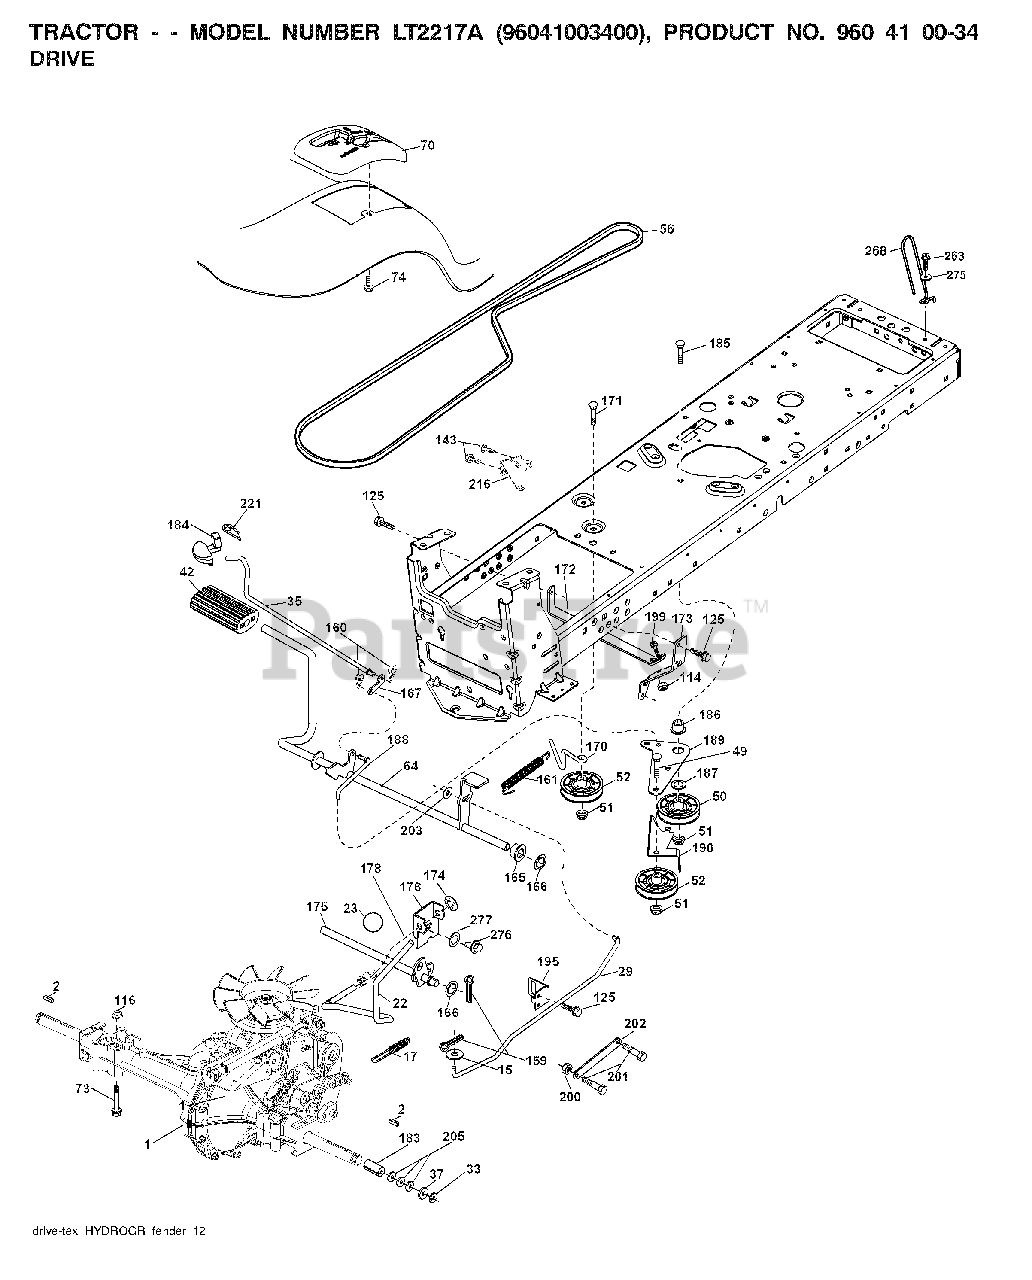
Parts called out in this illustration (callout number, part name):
2	SQUARE KEY
17	SPRING.BRAKE.HG3000/3500
22	ROD.SHIFT.FENDER.TLT.2006
23	KNOB.DUCKHEAD.1/2
29	ROD.BRAKE.HG-0510
33	E-RING LT
35	ROD.BRAKE.PARKING.LT.T
42	PEDAL COVER T
49	BOLT
50	IDLER.FLAT.910.OFFSET
51	NUT LOCK FLG 3/8-16 UNC
52	IDLER.V-GROOVE.910.OFFSET
64	SHAFT.ASM.PEDAL.BRAKE.
70	CONSOLE.SHIFT.STL.HYD.BLACK
73	BOLT.HEX.FLNG.5/16-18X3.75
74	SCREW.HI-LO.CONSOLE
114	NUT.71038.31-18.HEX.NYLOCK
116	NUT LOCK HEX FLANGE 5/16-18
125	SCREW
159	COTTER PIN
160	RETAINER CLIP
161	SPRING.RETURN.CLUTCH.2006
162	SPACER.TRANSAXLE.18&22
165	BUSHING.SHAFT.BRAKE.HAND
166	NUT.PUSH.625.2006
167	LATCH.BRAKE.SPRING
170	KEEPER.V-IDLER.CENTER.
172	STRAP.TRQ.LH.FS.HG0510
173	STRAP TORQUE RH
174	NUT.PUSH.500.2006
175	SHAFT.ASM.SHFT.HG0510/
176	ARM.CLEVIS.ROD.SHIFT
178	SPRING.SHIFT.GT2006
183	SPACER AXLE
184	HANDLE.PAKRING.BRAKE.
186	SPACER.RETAINER
187	WASHER 12/32X2X10GA
188	LINK.CLUTCH.GROUND.DRIVE
189	BELLCRANK.GROUND.DRIVE.TEX.
190	KEEPER.BELLCRANK.DRIVE
195	BRKT.ROD.BRAKE.18/20/2
199	BOLT
200	NUT.CENTERLOCK.5/16-
201	BOLT SHOULDER 5/16-18 UNC
202	LINK TRANS
203	WASHER
216	BRACKET.PULLEY.IDLER.W/TEX
221	RETAINER CLIP
231	IDLER.V-GROOVE.1.688.OFFSET
263	SCREW, 3/8-16X3/4
275	WASHER
276	BOLT FIN HEX 7/16-14 X 1
277	WASHER SERRATED
